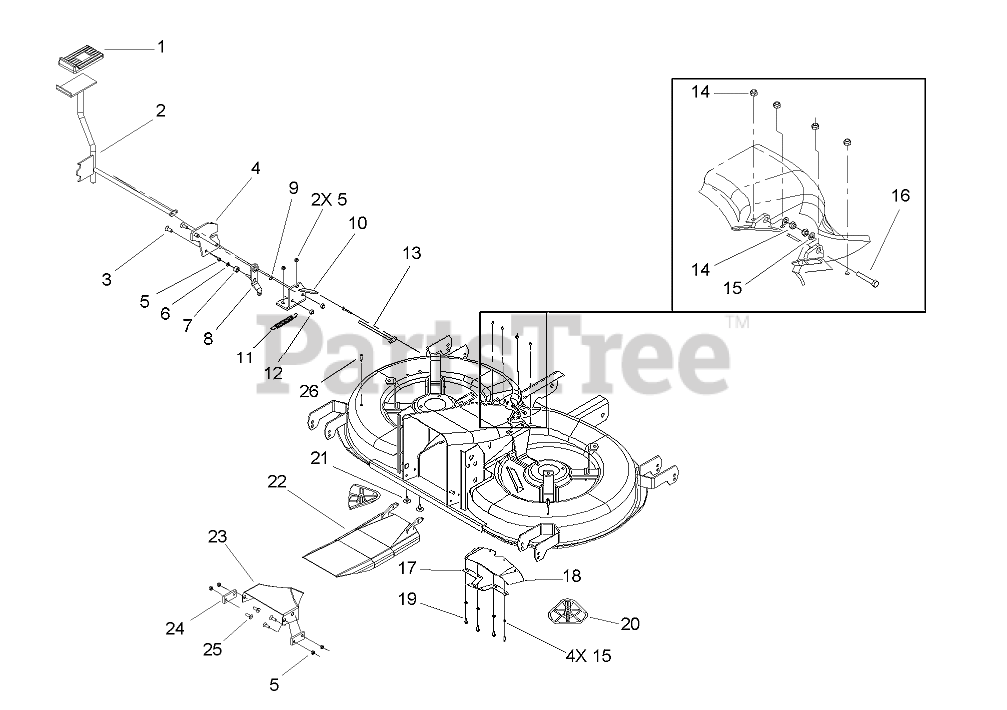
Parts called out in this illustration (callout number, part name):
1	Cover-Lever, FOOT
2	Lever-Foot
3	SCREW-HSFH
4	Plate-Stop
5	NUT-LOCK
6	WASHER-FLAT
7	Roller
8	Lever-Spring
9	RING-LOCKING
10	Bracket-Mounting
11	Spring
12	NUT
13	Rod-Door, Mulch
14	NUT-LOCK
15	WASHER
18	Gasket-Door, Mulch
19	Screw-HH
20	Kicker
21	SCREW-CARR
22	Door-Mulch
23	Baffle-Center
24	PLATE-BAFFLE, CENTER
26	SCREW-TAP, PPH
